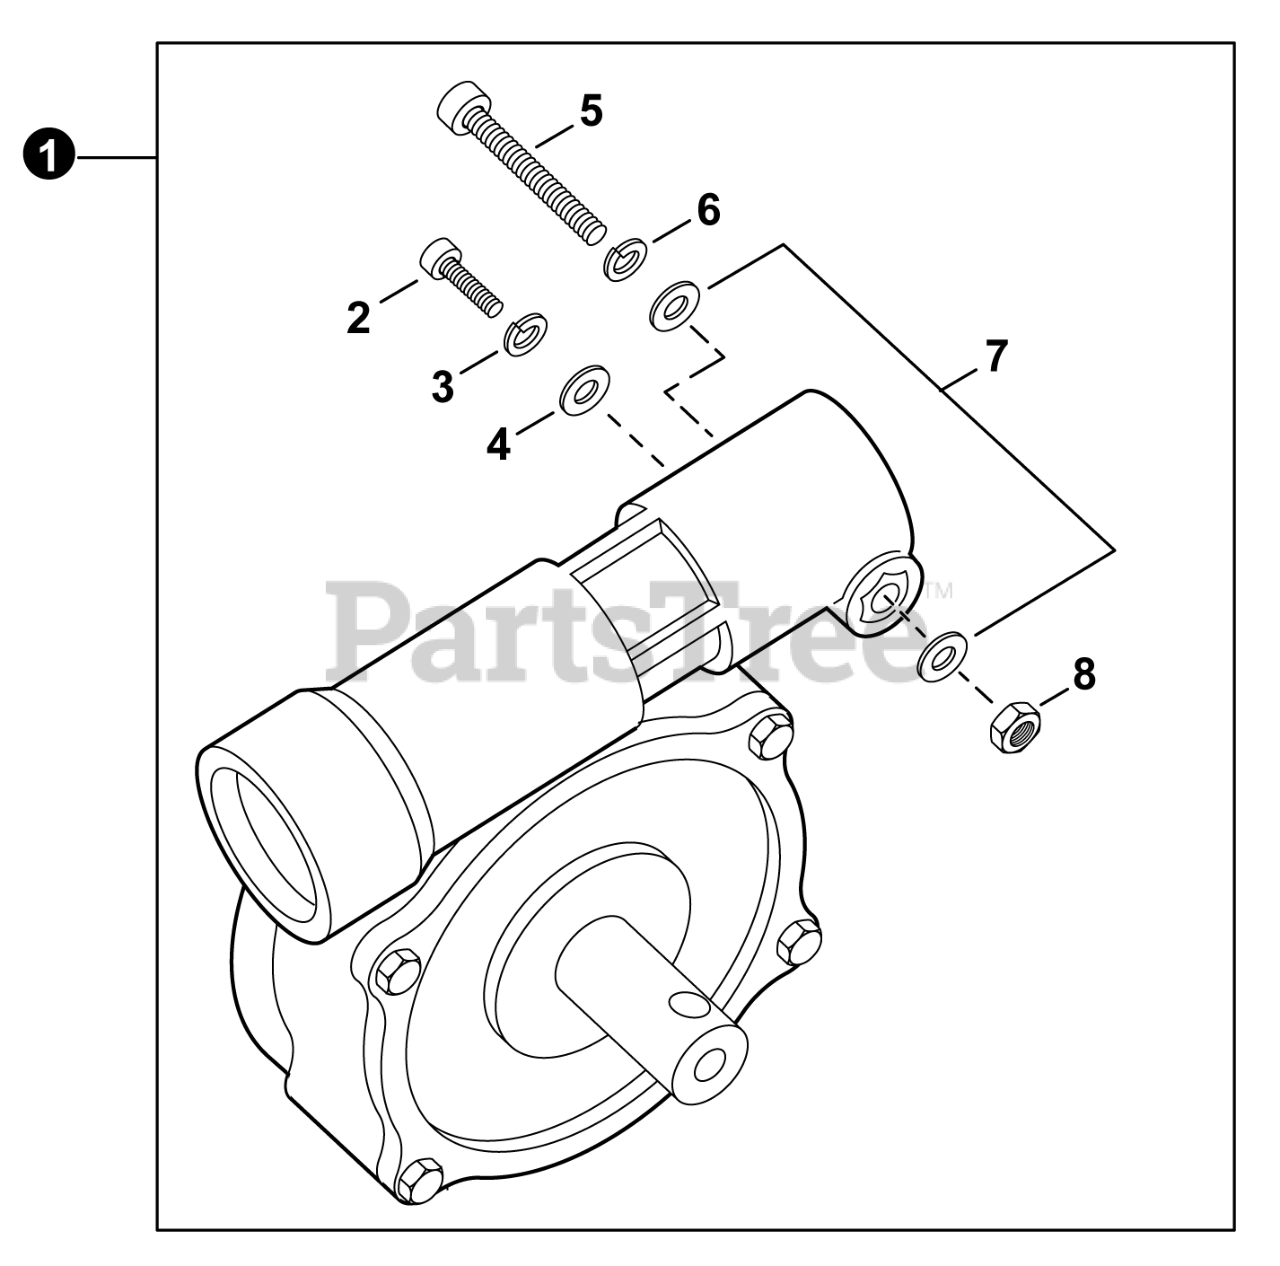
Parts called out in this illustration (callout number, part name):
1	GEAR CASE ASSY - 25MM
2	BOLT 5x12
3	WASHER, SPRING 5
4	WASHER, FLAT 5.5x10x0.8
5	SCREW, SOCKET HEAD 6x30
6	WASHER, LOCK M6
7	WASHER M6
8	NUT, HEX M6
